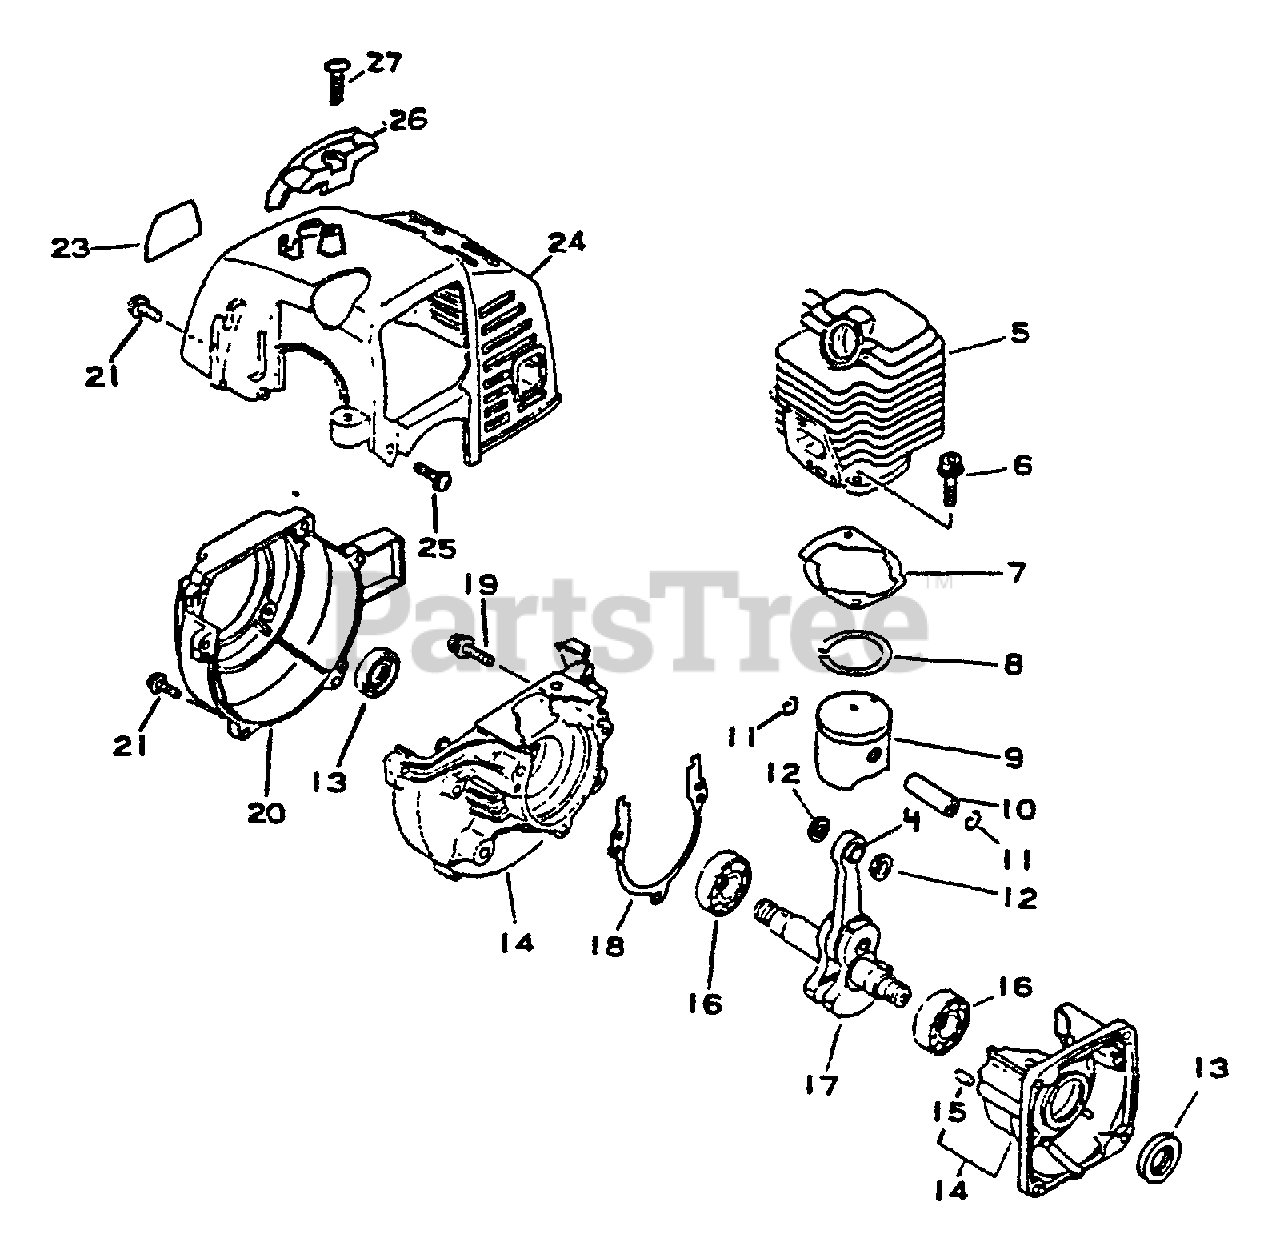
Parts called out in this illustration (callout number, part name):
4	BEARING, NEEDLE
5	CYLINDER
6	SCREW - 5X22
7	GASKET, CYLINDER
8	RING, PISTON
9	PISTON
10	PIN, PISTON
11	RING, RETAINING
12	SPACER, PISTON
13	SEAL, OIL
14	CRANKCASE KIT
15	PIN - LOCATING
16	BEARING, BALL - 6201
17	CRANKSHAFT ASSY
18	GASKET, CRANKCASE
19	SCREW - 5X28
20	CASE, FAN - ORANGE
21	SCREW - 4X16
23	LABEL - MODEL 2310
24	COVER, ENGINE
25	SCREW - 4X12
26	GUARD, TOP - BLACK
27	SCREW - 5X16 -- TAPPING
